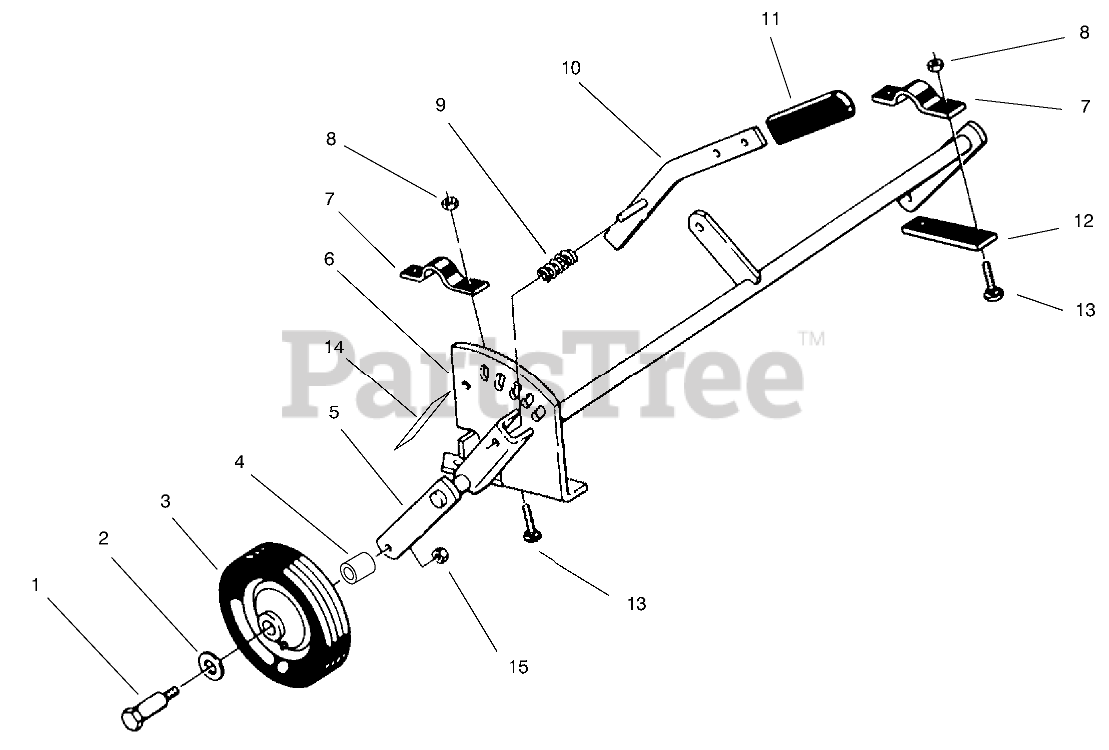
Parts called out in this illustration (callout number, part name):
1	SCREW-HH
2	WASHER-FLAT
3	ASSY-GAUGE WHEEL
4	SPACER
5	Gage Wheel Support
6	Quadrant
7	Clamp
8	NUT-LOCK, NI
9	SPRING-COMPRESSION
10	Lever
13	BOLT-CARR
14	DECAL-HOC
15	NUT-HEX
